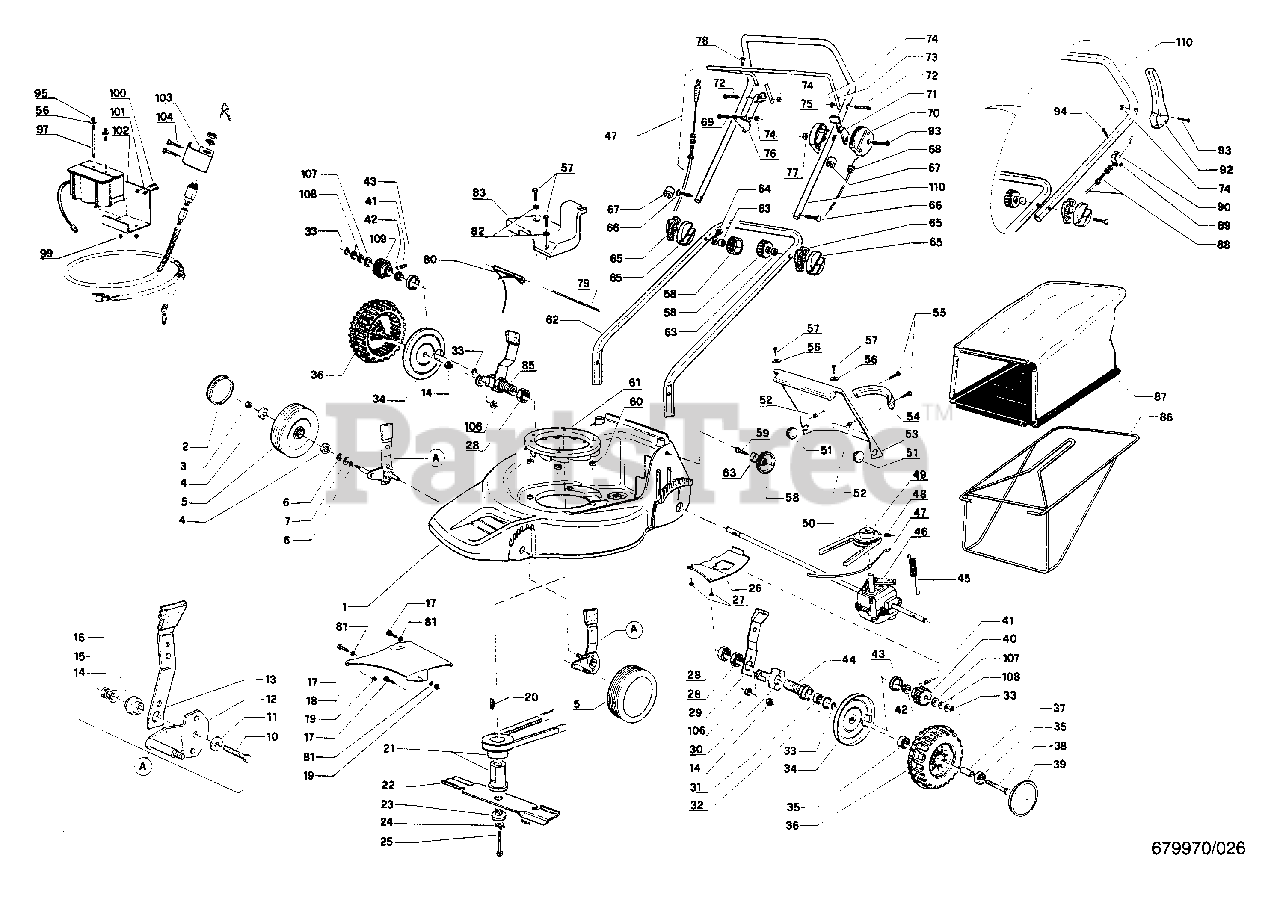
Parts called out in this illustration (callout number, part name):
2	Cover Wheel
4	Bearing
5	Wheel Front
12	Bracket, Wheel
13	Height adjuster, Front
16	Bushing
18	Deflector
20	Woodruff Key
21	Pulley Drive
26	Deflector
29	Height Adjuster, Rear
30	Bracket
31	Bearing
34	Wheel Guard
35	Bearing
36	Wheel, Rear
37	Bushing
39	Cover, Wheel
46	Gear Box
51	Bump, Flap
54	Flap Handle
61	Cooling Flange
62	Lower Handle
64	Washer, Clip
65	Coupling Half
68	Cable (130) B & S
70	Box Half
73	Lever Traction
75	Box Half
76	Bracket
83	Bracket
86	Frame, Bag
88	Cable B & S
90	Bracket
102	Bracket
103	Bracket
110	Handle, Upper
